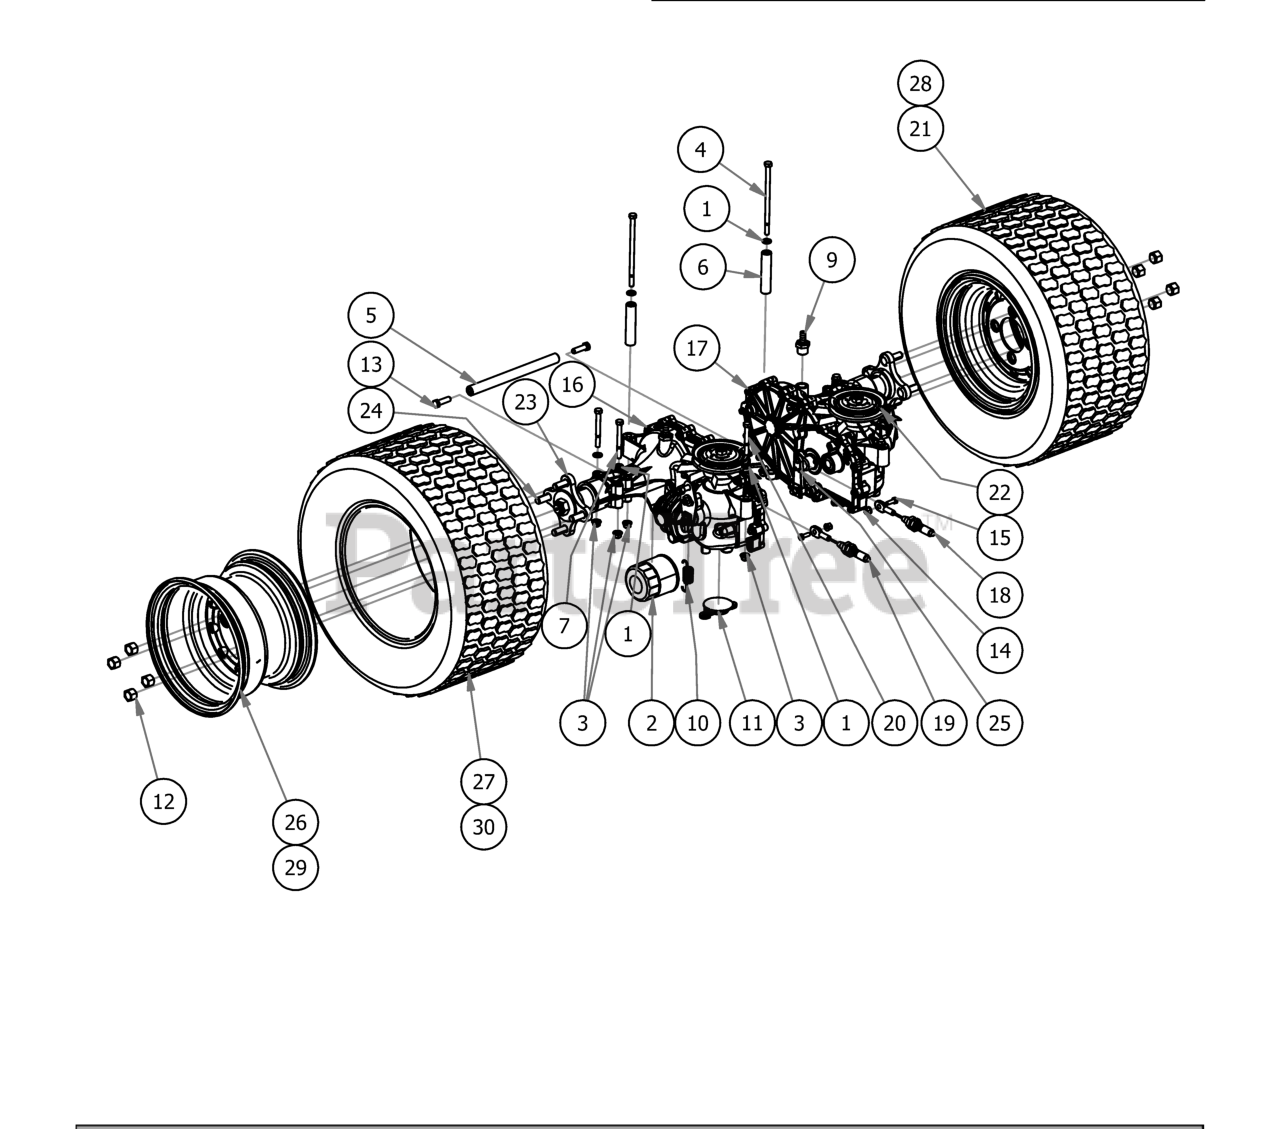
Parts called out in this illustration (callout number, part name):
1	5/16" Flat Washer
3	5/16-18 Nylon Flange Nut
4	5/16" x 6" Bolt
5	2017 Transaxle Spacer-ZT
6	2017 Transaxle Spacer
7	5/16" x 3" Hex Bolt
9	45 degree fitting
10	Transaxle Spring
11	ZT Transaxle Charge Plate/With O'Ring
12	Acorn Lug Nut
13	3/8'' x2'' Hex Bolt
14	1/4-20 Nylon Insert flange Nut
15	1/4" x 3/4" Hex Bolt
16	Right ZT Transaxle
17	Left ZT Transaxle
18	Brake Cable,18.5"
19	Brake Cable, 24.5"
20	5/16" x 2 1/2" Bolt
21	ZT Tire and Rim Assembly 22 x 11 - 10
22	Fan/Pulley Kit for ZT
23	Transaxle Hub
24	Transaxle Wheel Studs
25	Transaxle Brake Lever
26	ZT Black Wheel Only
27	ZT Tire Only 22x-11-10
28	48" ZT Only Tire 22x10-10 Tire and Wheel
29	48" ZT Only 10" Black Wheel
30	48" ZT Only 22x10-10 Tire
